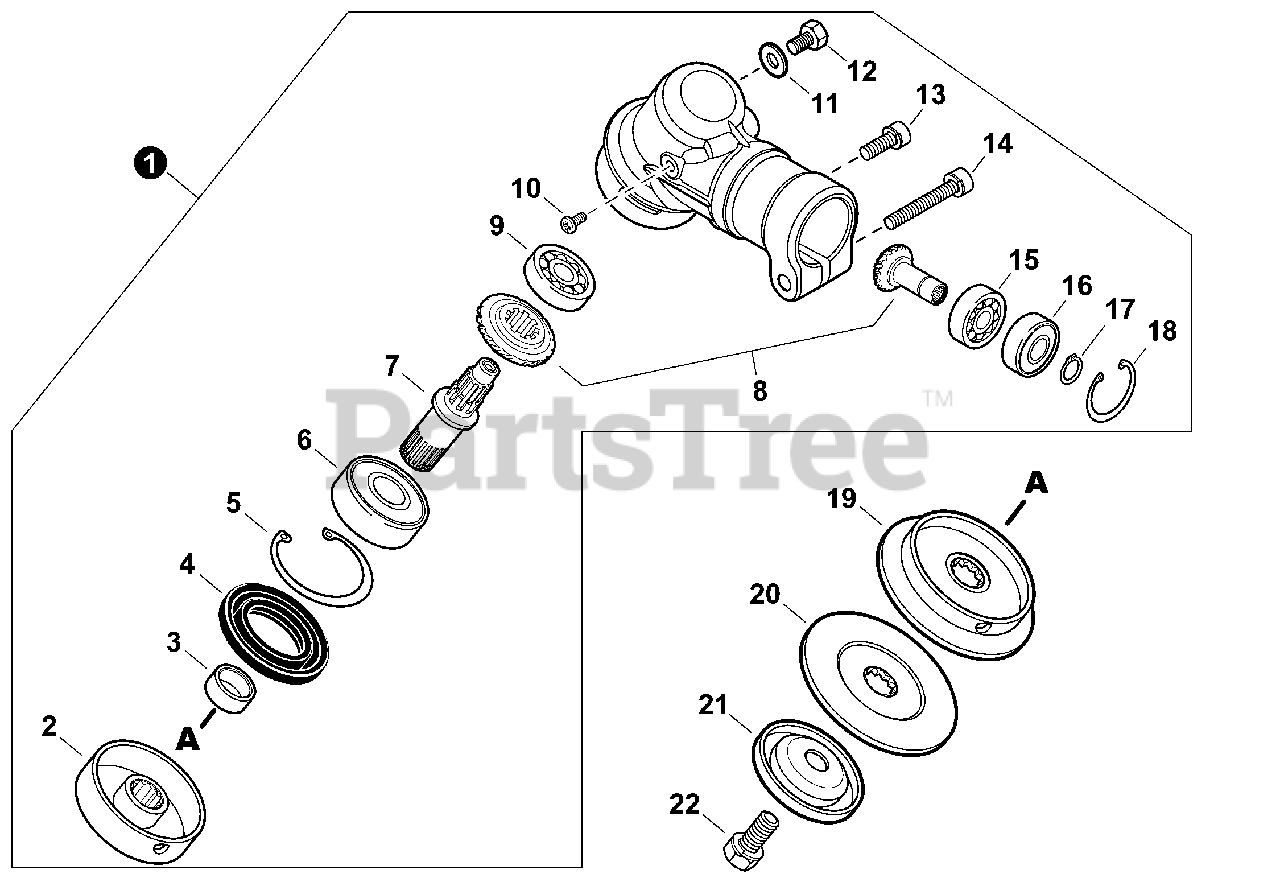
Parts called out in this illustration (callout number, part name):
1	GEAR CASE ASSY
4	SEAL, OIL
5	RING, SNAP Ø32
6	BEARING, BALL 6201
7	SHAFT, GEAR
8	GEAR SET
9	BEARING, BALL 609
10	SCREW M4×6
11	WASHER 6.5×11.5×0.8
12	BOLT M6×10
13	BOLT M5×10
14	BOLT M6×40
15	BEARING, BALL 6000
16	BEARING, BALL 6000ZZ
17	RING, SNAP Ø10
18	RING, SNAP Ø26
19	PLATE, ADAPTOR - UPPER
20	PLATE, ADAPTOR - LOWER
21	GUARD, BOLT
